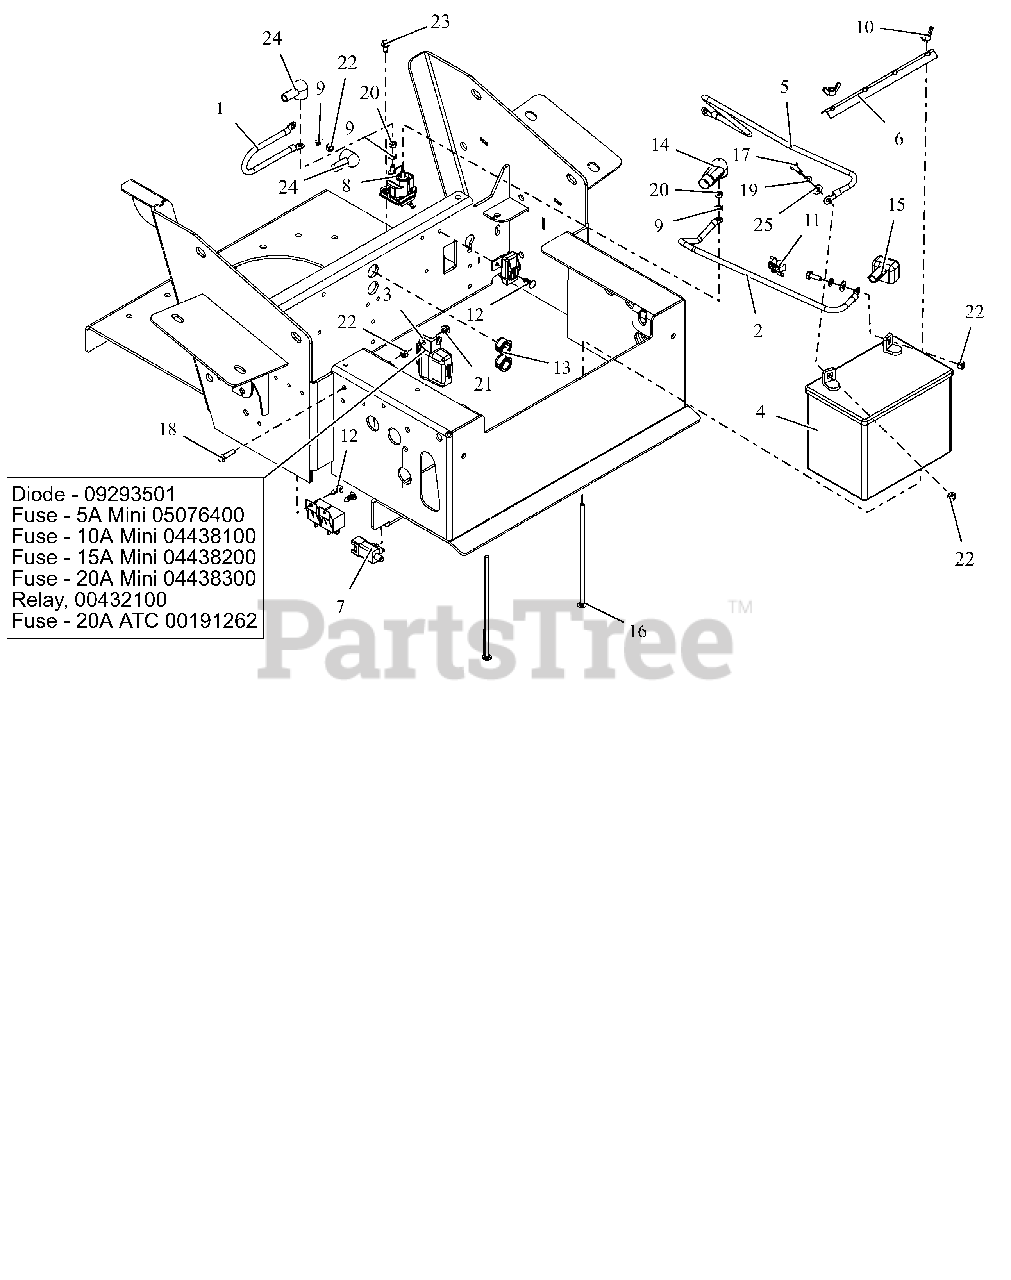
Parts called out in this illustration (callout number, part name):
1	CABLE, POS W/(2)1/4 RING 9.0LG
2	CABLE,POS W/(2)1/4 RING 21.5LG
3	HARNESS, PT WIRE
3	DIODE, CONNECTOR SHELL
3	FUSE, 5 AMP MINI-ATC
3	FUSE,10 AMP MINI-ATC
3	FUSE,15 AMP MINI-ATC
3	FUSE,20 AMP MINI ATC
3	RELAY,SEALED W/DIODE
3	FUSE, 20 AMP BLADE S/O
4	BATTERY, 300 CCA 10U1L
5	CABLE-NEGATIVE BATTERY 24.00"
6	HOLD DOWN
7	SWITCH, SNAP IN - N.O./N.O.
8	SOLENOID, STARTER (SEALED)
9	@WSHR-LK-EXT.262X.502X.026YWZC
10	NUT-LK WING .250-20 YWZC
11	CLIP,T,.31-.38,
12	RIVET, .25 NYLON PANEL
13	BUSH, PANEL SNAP .687X.875X.56
14	BOOT, .65ID POS
15	INSULATOR
16	BLT-RDHDSQNK .25-20X7.50 GR2YZ
17	@BLT-HEX .25-20X.75 GR5 YWZC
18	@BLT-HEX .25-20X1.00 GR5 YWZC
19	@WSHR-LK .25X.062 REG YWZC
20	NUT-HEX M6X1.0 YWZC
21	@NUT-LK-NYL-FLG .25-20 YWZC
22	@NUT-HEX .25-20 YWZC
23	SCR-TAP .25-20X.50 HWH TR YWZ
24	BOOT, EYELET TERMINAL
25	@WSHR-FL-STL.281X.62X.065 YWZC
